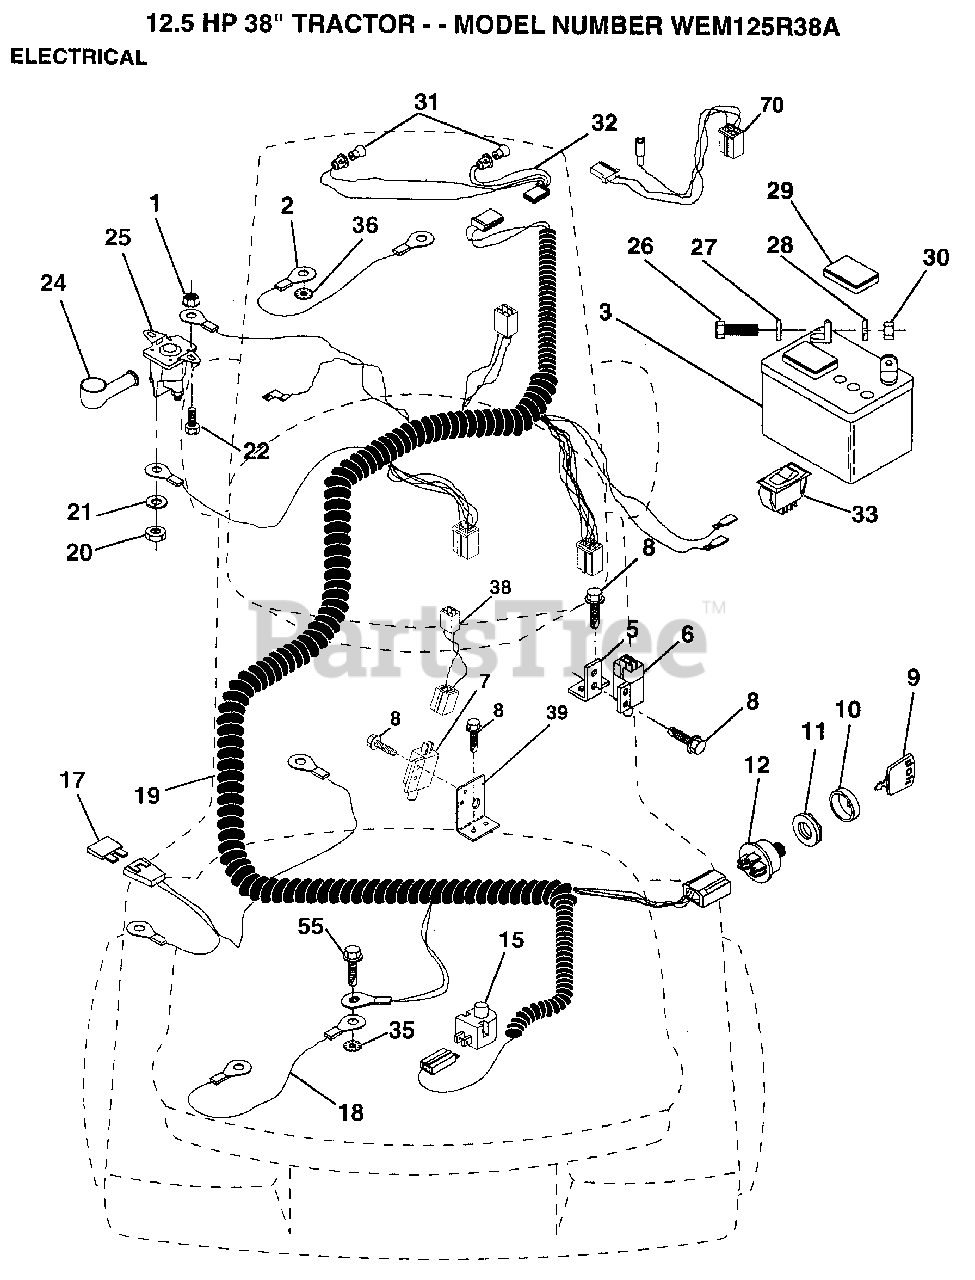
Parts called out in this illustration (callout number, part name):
1	NUT
2	CABLE ASM.
5	BRACKET LT
6	SWITCH INTERLOCKT
7	SWITCH-INTER. GT
8	SCREW
9	KEY STEEL DELTA
10	COVER KEY SWITCH
15	SWITCH SEAT
17	FUSE HYT
18	CABLE ASSY
19	HARNESS.IGN.FEND.
20	NUT
22	BOLT
26	BOLT LT
27	WASHER
28	LOCKWASHER
29	"CAP,BATTERY "
31	HEADLAMP BULB
32	"HARNESS,LIGHT SOC"
33	SWITCH LT
35	LOCKWASHER.5/16.E
36	LOCKWASHER
38	ADAPTER.HARN.SERV
39	BRACKET SWITCH CLUTCH
55	SCREW LT
70	HARNESS ENG DUAL
